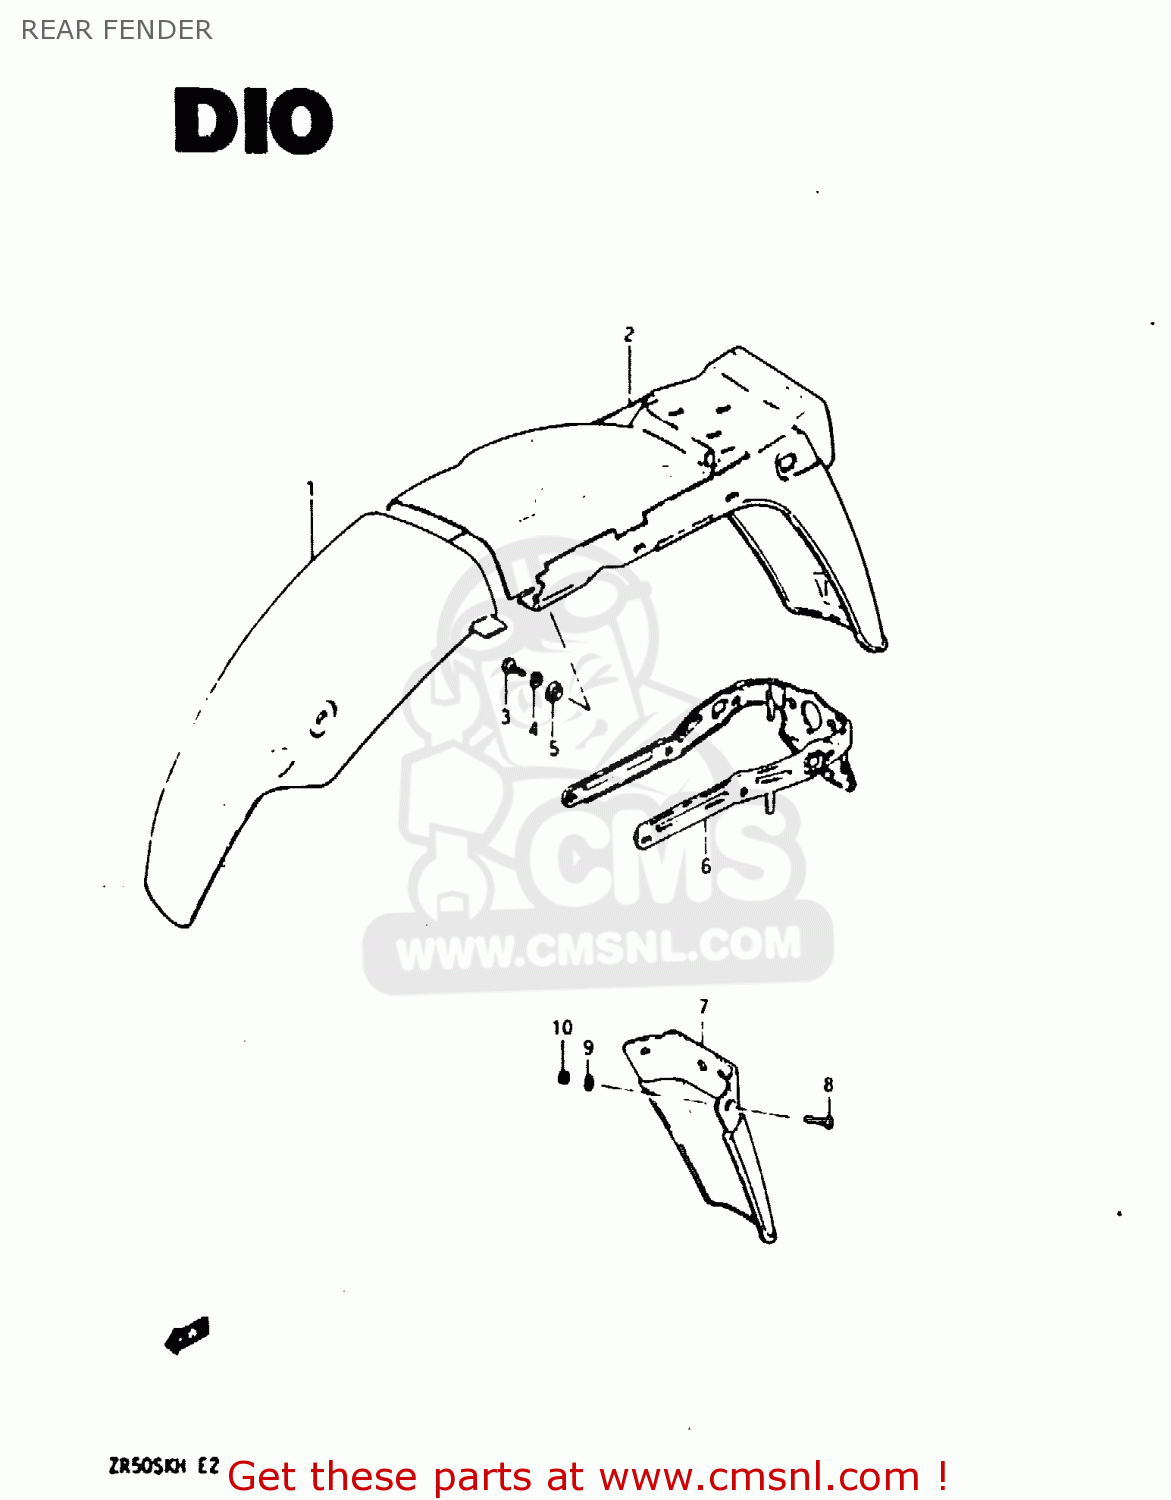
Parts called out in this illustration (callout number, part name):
1	BODY,RR FENDER FR
2	FENDER, REAR
3	BOLT
4	WASHER,LOCK
5	WASHER
6	REINFORCEMENT, REAR FENDER
7	EXTENSION, REAR FENDER
8	SCREW
9	WASHER 4MM
10	NUT
